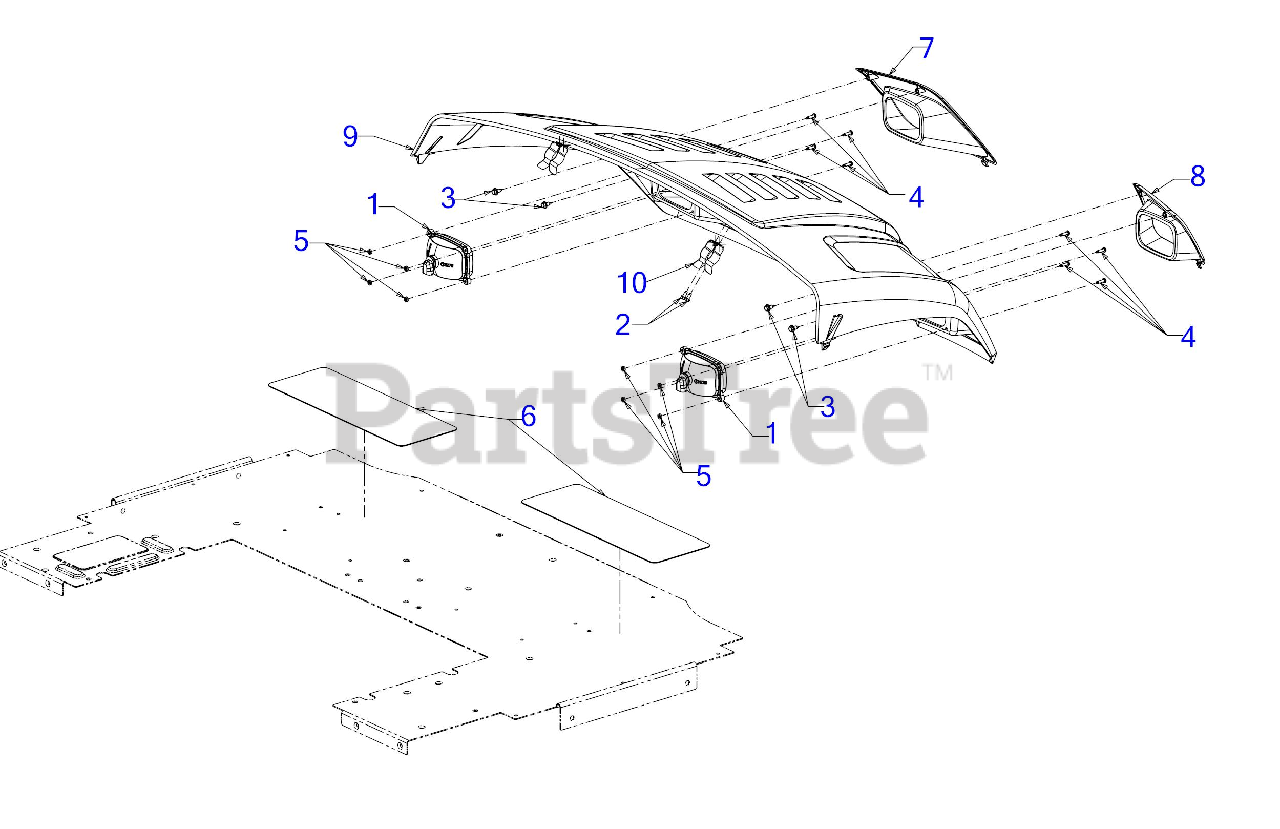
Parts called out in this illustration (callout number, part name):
1	HEADLIGHT ASSEMBLY
1	HEAD LAMP BULB
2	HEX SCREW #12-16 x .50
3	SCREW 1/4-20X.625
4	SCREW #10-24 x .750
5	LOCK NUT 10-24
6	FOOT REST PAD
7	HEADLIGHT BEZEL (LH)
8	HEADLIGHT BEZEL (RH)
9	UV HOOD
10	HOOD LATCH SPRING
